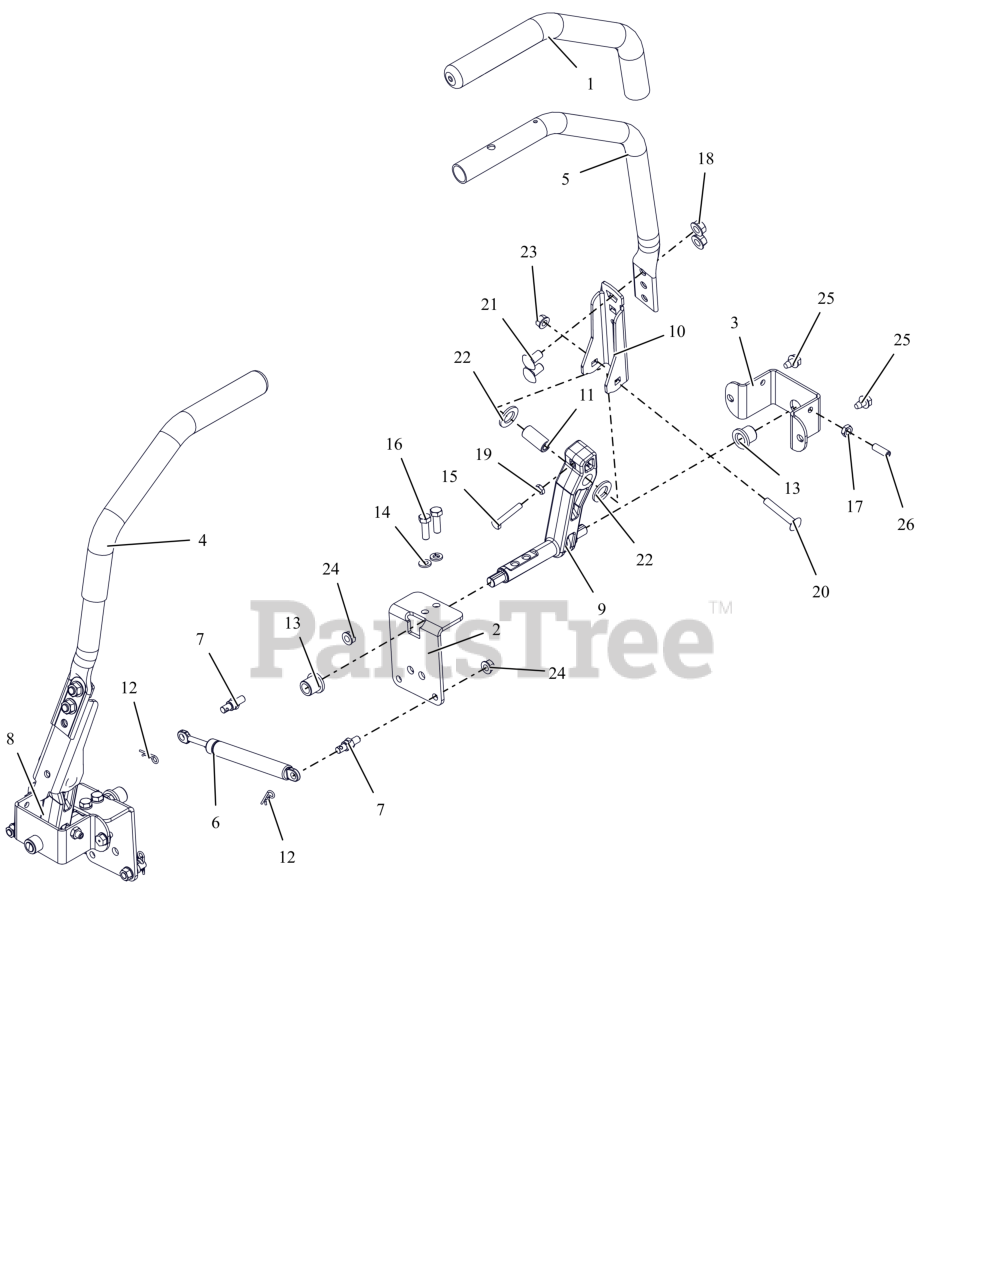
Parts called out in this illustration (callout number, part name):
1	GRIP, HANDLEBAR 15" FOAM
2	BRKT, STEEERING
3	BRKT, STEERING
4	HANDLE, STEERING-RH
5	HANDLE, STEERING-LH
6	DAMPER, STRAIGHT MOUNT
7	COUPLER, DAMPER MOUNT
8	STEERING, RH LWR CAST ARM
9	STEERING, LH LWR CAST ARM
10	ARM, CONTROL UPPER
11	BSHG-SLV .342 X .627 X 1.331
12	PIN, HAIR #213 .08X1.19 ZCC
13	BHSG-FLG .500X.750X.750X.125
14	WSHR,LK-REG .312X.078 ZCC
15	BLT, HEX .25-20X1.50F G5 ZCC
16	BLT, HEX .31-18X1.00 G8 ZCC
17	NUT-JAM .312-18 G2 ZCC
18	NUT-LK-CTR-FLG .375-16 GF ZCC
19	NUT-JAM .250-20 G2 ZCC
20	BLT, RHSSN .31-18X2.00 G5 ZCC
21	BTL,RHSSN .375-16 X 0.75 G5 FPB
22	WSHR, FRICTION
23	NUT,LK-CTR-FLG .31-18 GF ZCC
24	NUT-LK-TOP-FLG .312-18 GF ZCC
25	SCR,TAP .312-18X.50 HWH TR ZCC
26	SCR-SET, .312-18X1.000
